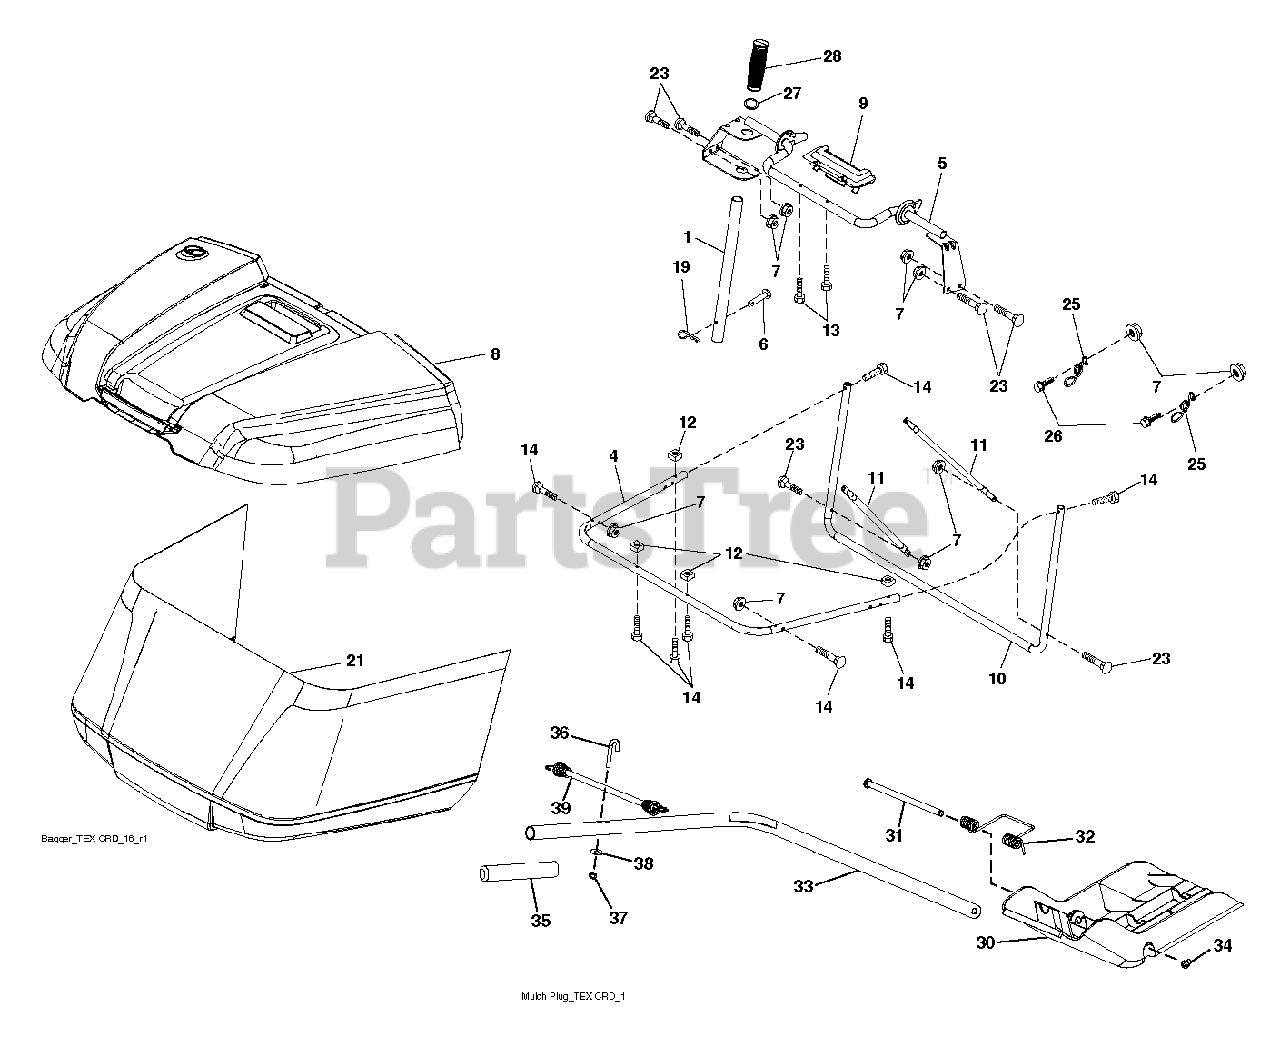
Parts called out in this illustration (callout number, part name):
1	TUBE.PNT.HDL.BAGGER.
6	RIVET,DRILLED
7	NUT T
19	PIN.COTTER.5/16.BOW TI
26	SCREW HEX CRT
28	GRIP.HANDLE.BLACK
34	E-RING.5/16"
38	WASHER
